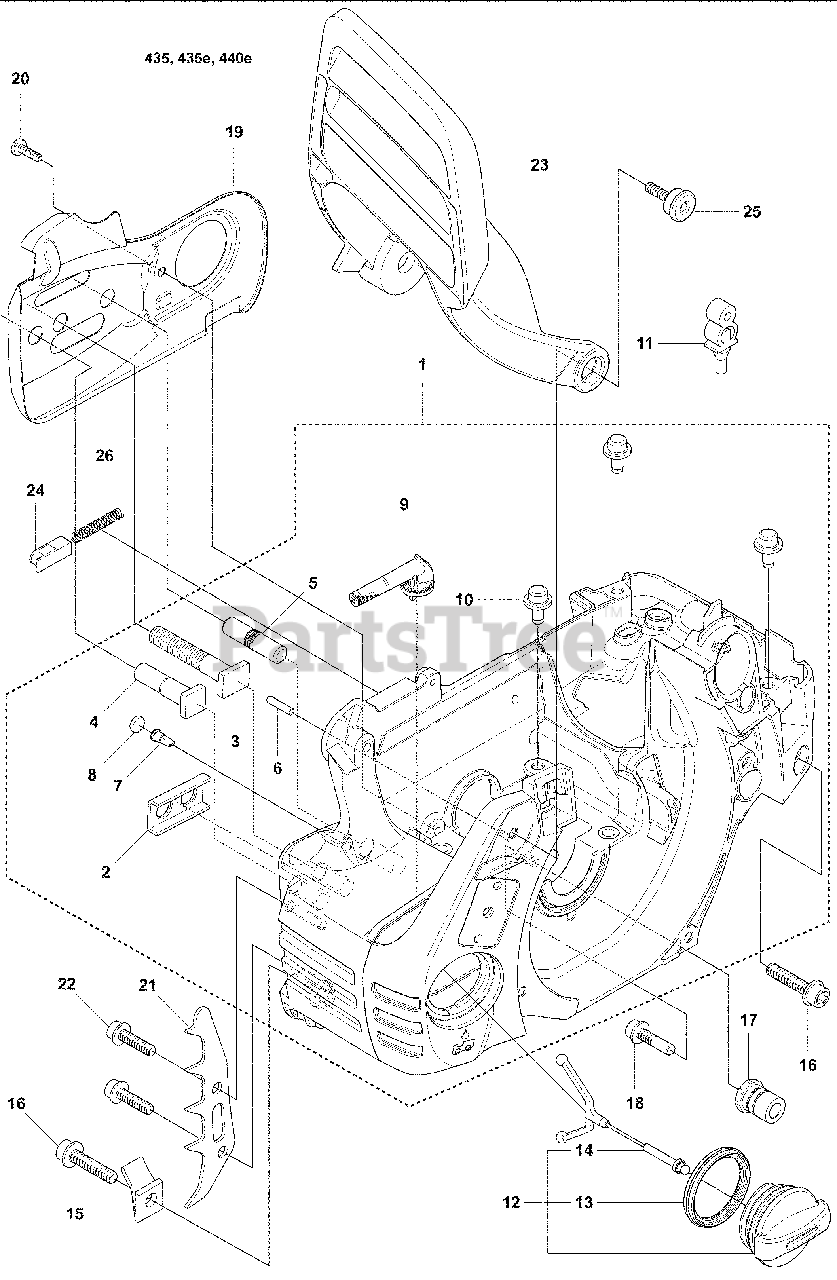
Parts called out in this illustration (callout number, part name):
1	Crankcase Assembly
2	Stiffening Plate
3	Bar Bolt
4	Bar Bolt, X2
5	Bar Bolt
6	Pin
7	Valve Check, Duckbill
8	Sintered Filter, Bronze
9	Oil Screen
10	GUIDE PEN
11	Support
12	Fuel Tank Cap Assembly, Grey
13	Sealing Gasket
14	Holder
15	Chain Catcher
16	Screw, 3 X 25 IHSCFT
17	Lateral Support
18	Screw, Ihscft
19	Chain Guide Plate
20	Screw
21	Spike, Inner
22	Screw
23	Hand Guard
24	Catch
25	Screw
26	Lock Spring
